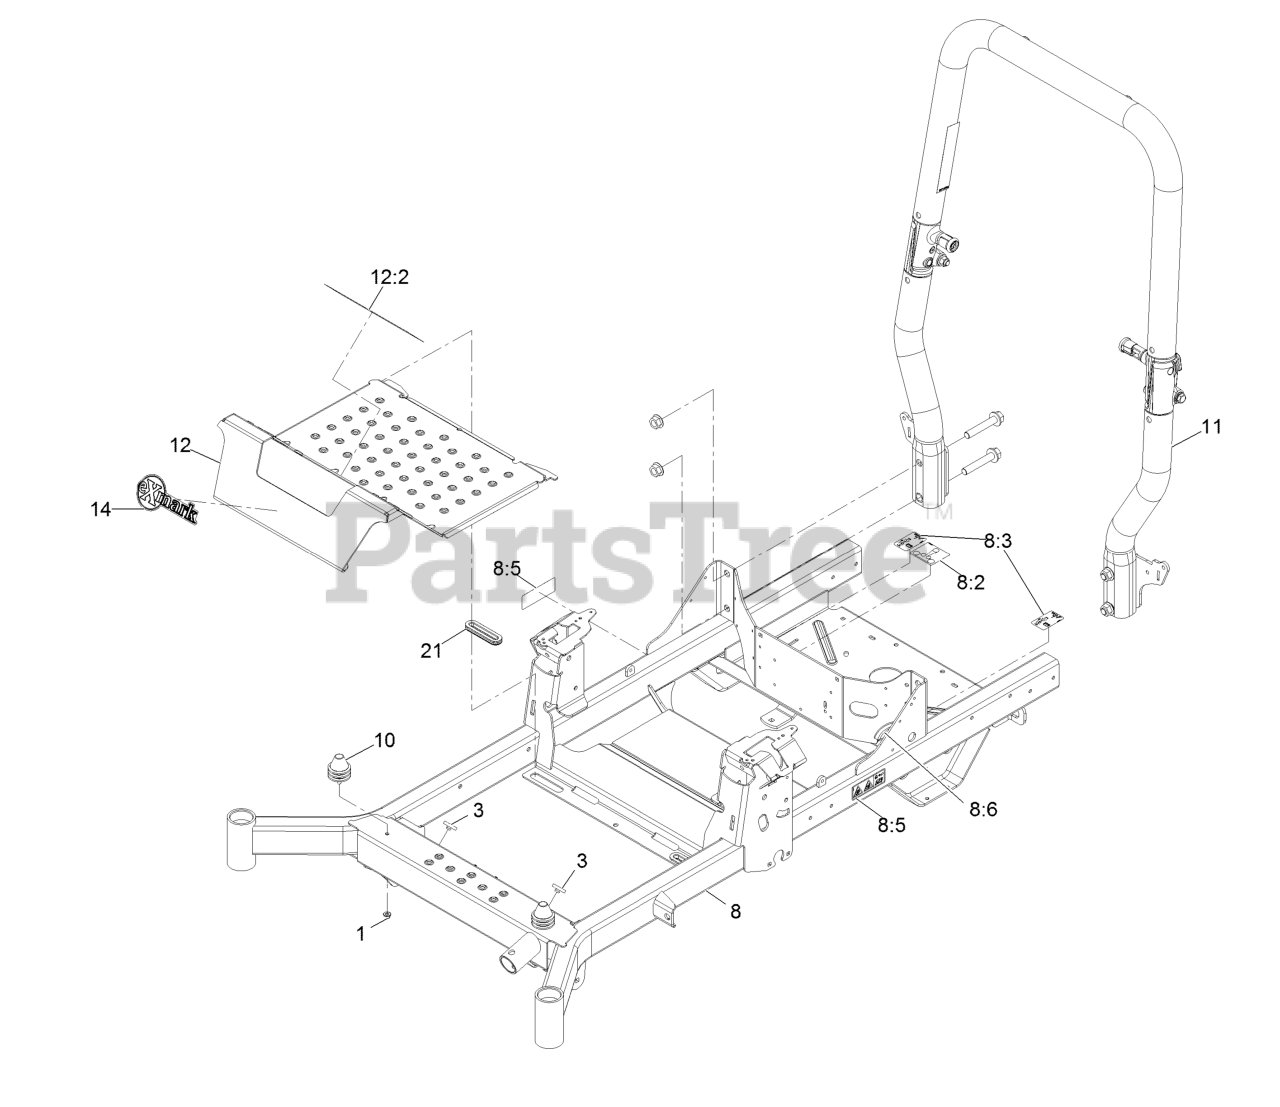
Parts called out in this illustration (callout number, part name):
1	Nut-Nyloc 5/16-18 Flg
3	Bumper-Push-In, Rubber
8	Frame ASM
8:2	Decal-Routing, Belt
8:3	Decal-Release, Drive
8:5	Decal-Warning
8:6	Strip-Seal
10	Isolator
11	ASM-ROPS Tapered
12	Pan-Floor
12:2	Decal-Danger
14	Decal-Exmark Logo
21	Grommet-Rubber
